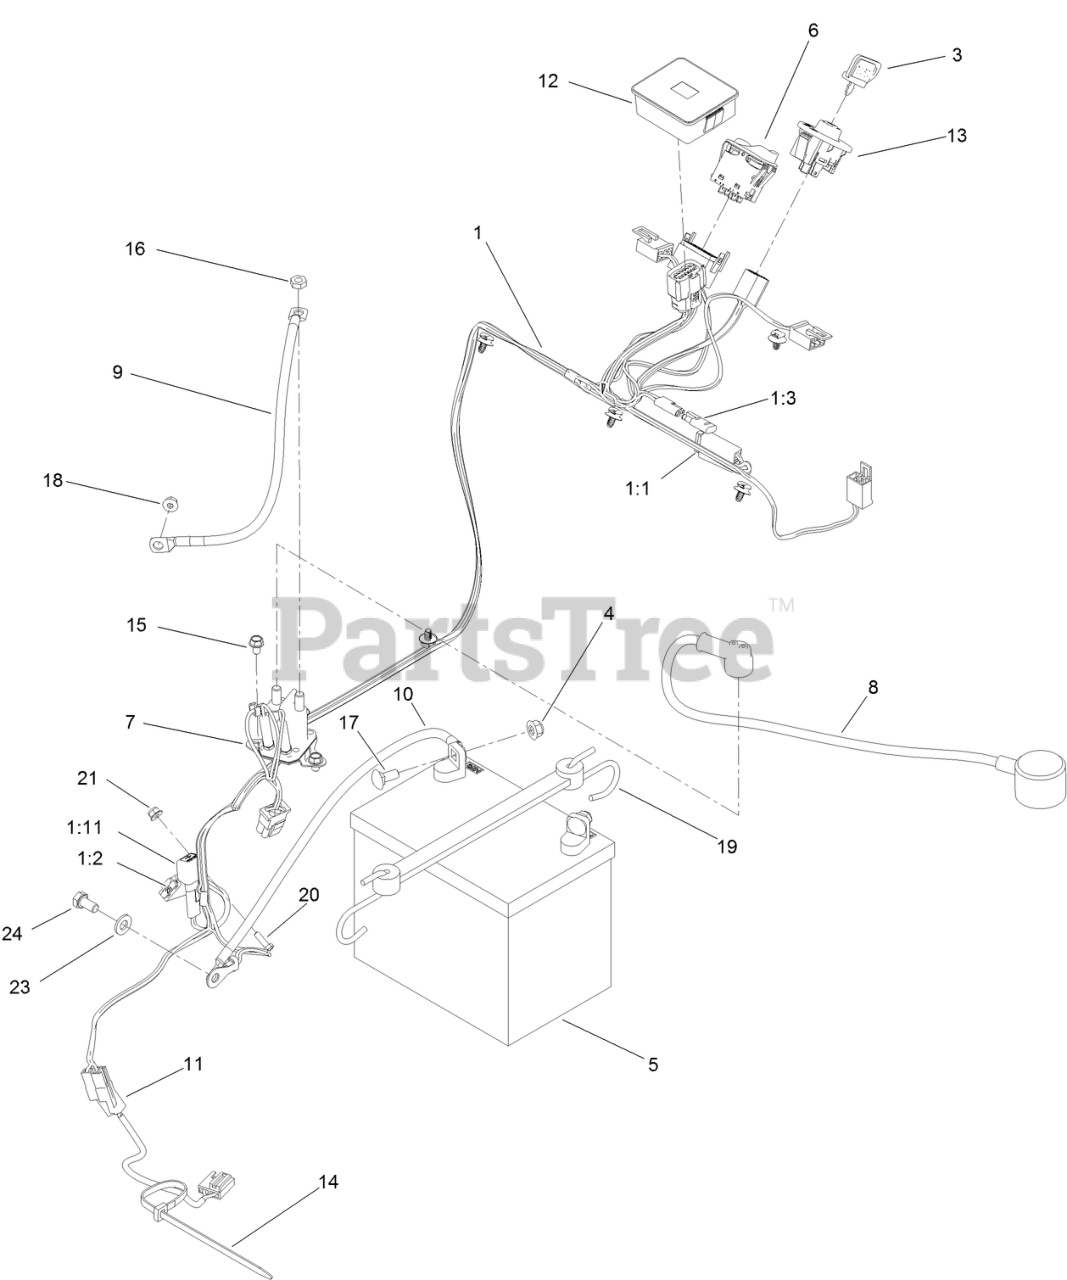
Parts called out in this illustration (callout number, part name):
1	HARNESS-WIRE, WASP
1:1	FUSE-BLADE, 15 AMP
1:2	FUSE-BLADE, 25 AMP
1:3	CAP-PLUG
3	KEY-IGNITION
4	NUT-HF, NI
5	BATTERY
6	SWITCH-ROCKER, (ON)-ON-OFF
7	SOLENOID
8	CABLE-BATTERY, POS ASM
9	CABLE-BATTERY, POS ASM
10	CABLE-BATTERY, NEG ASM
11	HARNESS-CLUTCH PIGTAIL
12	MODULE, HOUR METER
13	SWITCH-IGNITION
14	TIE-PLASTIC
15	SCREW-HWH
16	NUT-JAM
17	BOLT-CARR
18	NUT-HHF
19	HOLDDOWN-BATTERY
21	NUT-HF
23	WASHER-PLAIN
24	SCREW-HH
